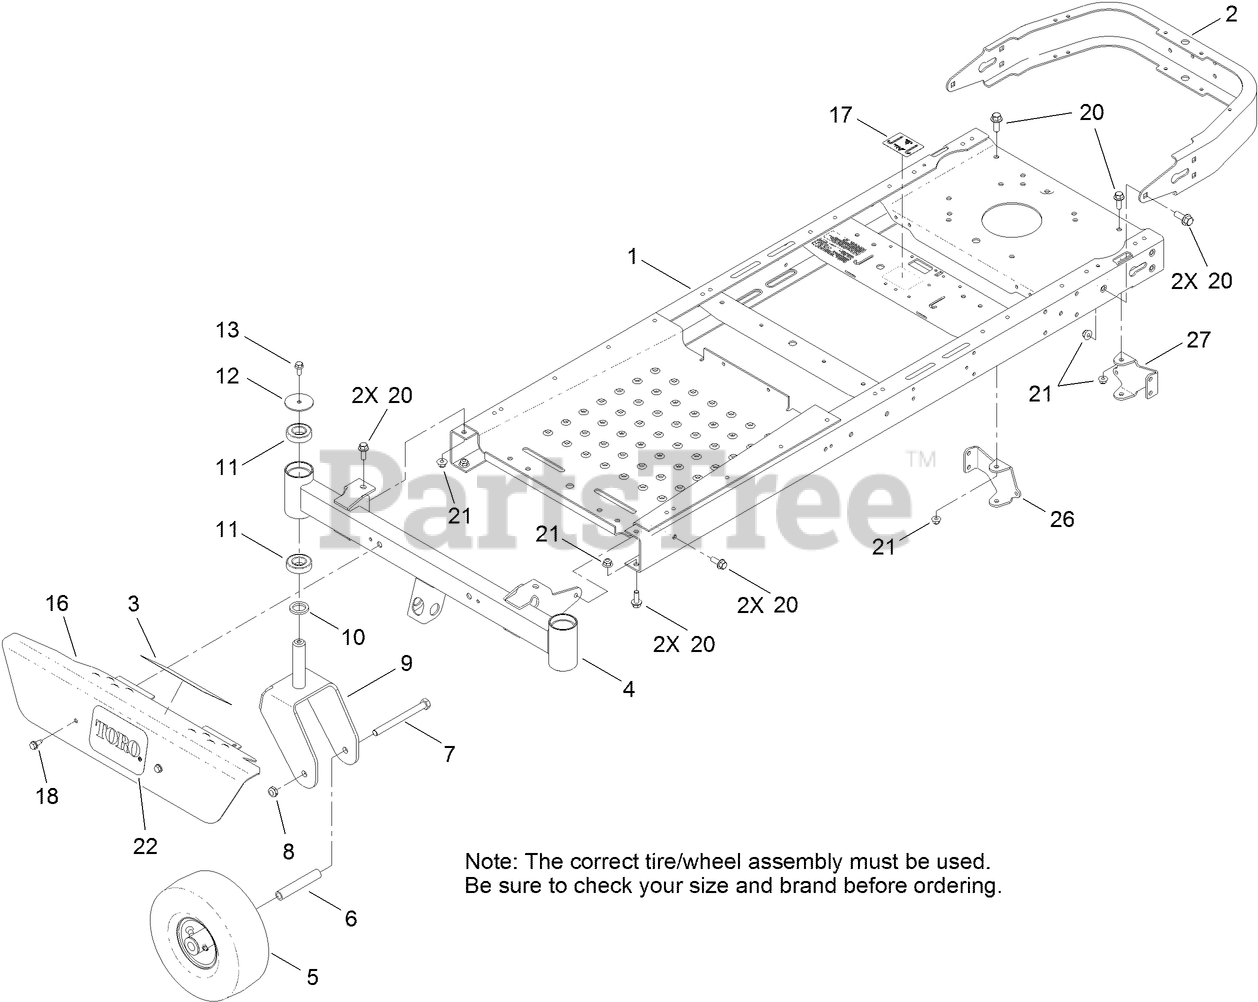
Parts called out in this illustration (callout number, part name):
1	FRAME ASM
2	BUMPER-REAR
4	AXLE-FRONT
5	CASTER WHEEL ASM
5	CASTER WHEEL ASM (CST)
6	BUSHING-SPANNER
7	SCREW-HH
8	NUT-HEX
9	FORK-CASTER
10	WASHER-THRUST
11	BEARING-BALL
12	WASHER
13	SCREW-HHF
17	DECAL-TRANSPORT
18	SCREW-HWHTF
20	SCREW-HHF
20	SCREW-HSBH
21	NUT-HF, NI
26	MOUNT-HYDRO, REAR (RH)
27	MOUNT-HYDRO, REAR (LH)
